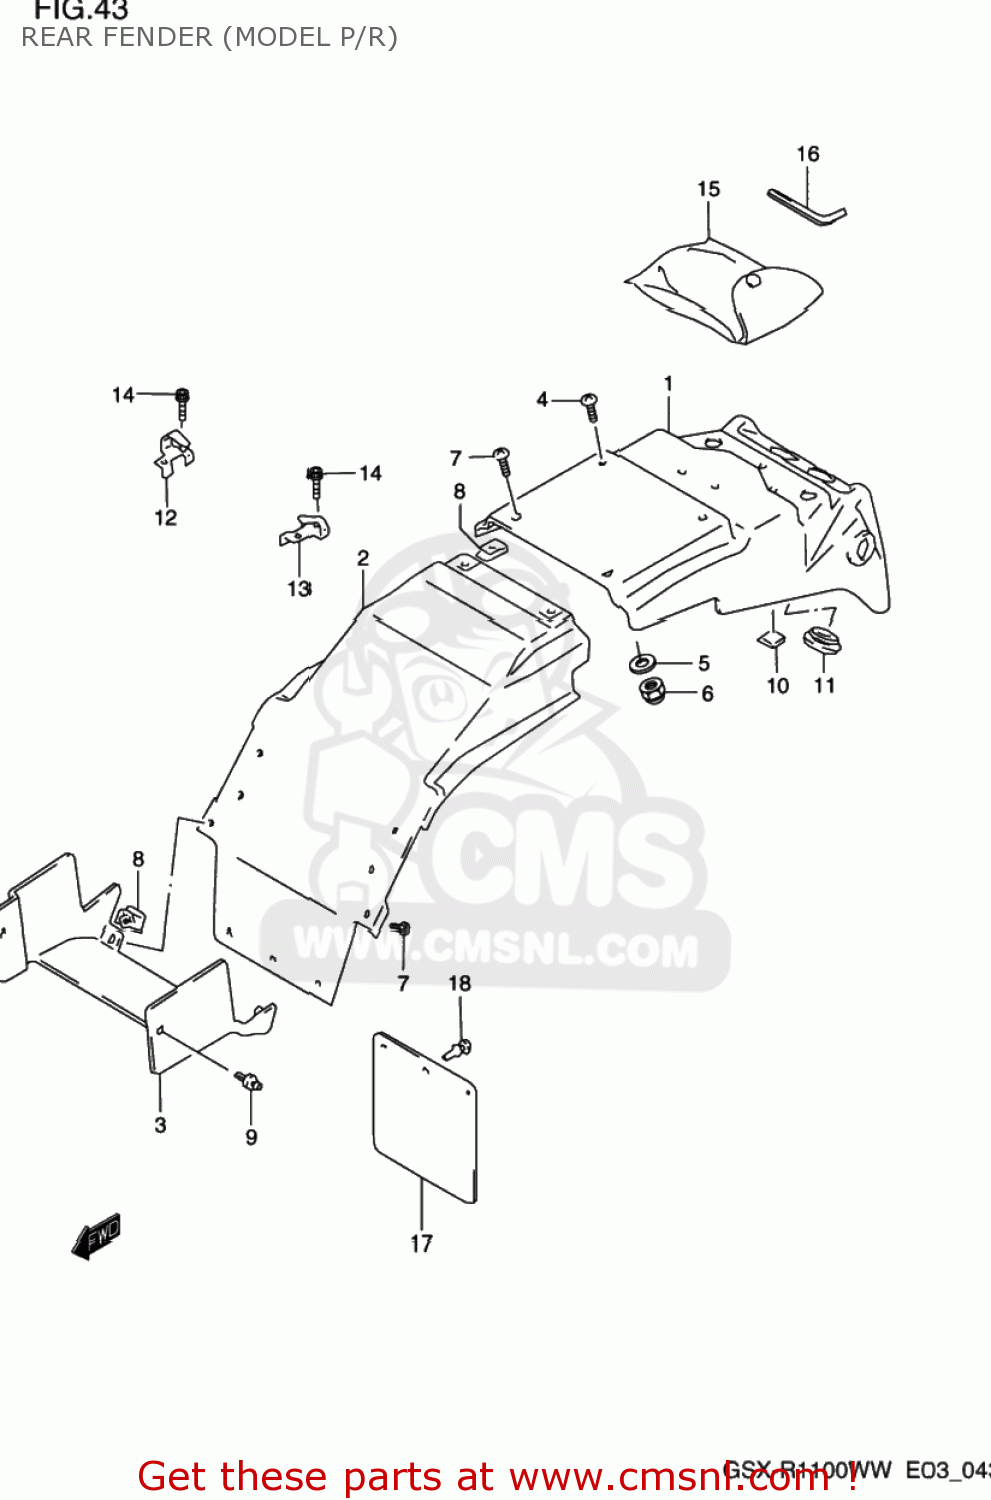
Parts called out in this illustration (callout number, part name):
1	FENDER,RR UPR
2	FENDER,REAR,UPPER,FRONT,N
3	FENDER,REAR,UPPER,FRONT,N
4	SCREW
5	WASHER
6	NUT
7	SCREW 5X12
8	NUT,HEADLAMP HOUSING,UPPER
9	CLIP
10	TAPE,REAR COMBINATION LAMP HOLE
11	CAP OD:40
12	HOLDER,HELMET,R
13	HOLDER,HELMET,L
14	BOLT
15	TOOL ASSY
16	SPANNER,HEXAGON(4)
17	GUARD,REAR FENDER MUD
18	CLIP,MUDGUARD
